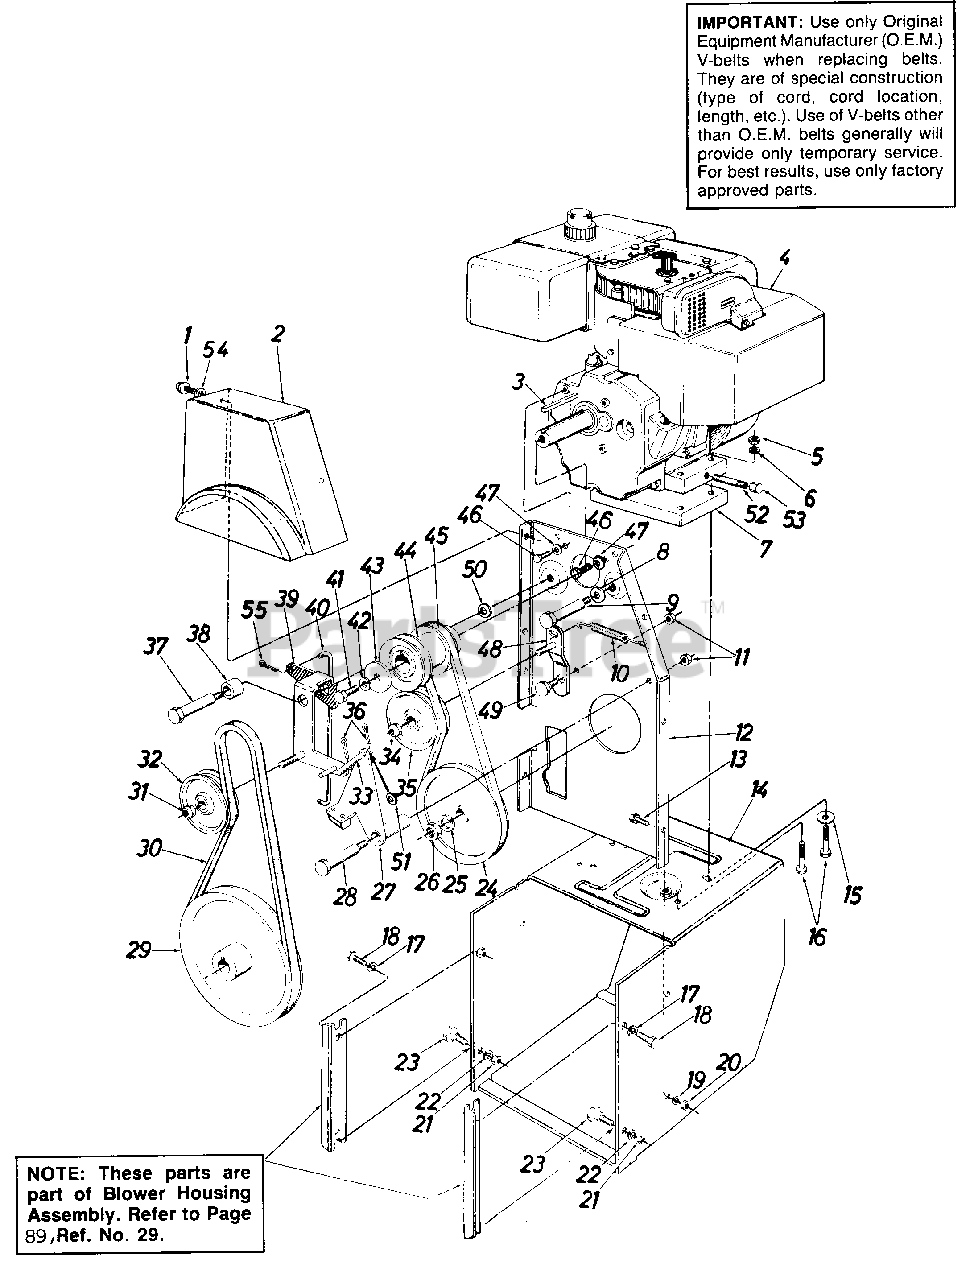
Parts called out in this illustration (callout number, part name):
1	Hex AB-Tap Scr. 5/16 x .75" Lg.
2	Belt Cover
3	Sq. Key 1/4" x 1.50" Lg.
4	Engine
5	Hex Nut 5/16-18 Thd.
6	L-Wash. 5/16" I.D.
7	Engine Spacer Ass'y.
8	Bell-Wash. .40 I.D. x .88 O.D.
9	Shld. Bolt .498" Dia. x 3.00" Lg.
10	Ext Spring .38 O.D. x 3.18" Lg.
11	Hex Cent. L-Nut 3/8-16 Thd.
12	Engine Brkt. Ass'y.
13	Hex Sems Scr. 5/16-18 x .75" Lg.
14	Frame Ass'y.
15	Fl-Wash. .345 I.D. x .75 O.D. x .060
16	Hex Bolt 5/16-18 x 2.50" Lg.
17	L-Wash. 3/8n I.D. H.D.
18	Pilot Scr. 3/8-16 x .88" Lg.
19	L-Wash. 5/16" I.D.
20	Hex Nut 5/16-18 Thd.
21	Hex Nut 3/8-16 Thd.
22	L-Wash. 3/8" I.D. H.D.
23	Shld. Bolt 498n Dia. x 840n Lg.
24	V-Pulley .628 I.D. x 7.50 O.D.
25	L-Wash. for 5/8n I.D.
26	Hex Ins. Jam L-Nut 5/8-18 Thd.
27	Brake Brkt. Ass'y.
28	Shld. Bolt 498n Dia. x 2.00" Lg.
29	V-Pulley .875 I.D. x 10.12 O.D.
30	"V"-Belt
31	Hex Ins. Jam L-Nut 3/8-24 Thd.
32	Fl-Idler w/Flanges 3.0 O.D.
33	Brake Linkage Ass'y.
34	Hex Ins. Jam L-Nut 3/8-24 Thd.
35	3.0" O.D. Fl-Idler w/Flanges
36	Int. Cot. Pin 8132n Dia.
37	Shld. Bolt .625" Dia. x 2.750" Lg.
38	Spacer .75 O.D. x 1.00" Lg.
41	Hex Bolt 3/8-24 x 1.25" Lg.
42	L-Wash. 3/8" I.D. H.D.
43	Fl-Wash.
44	Engine Pulley-Double Groove
45	"V"-Belt
46	Hex Bolt 5/16-24 x .62" Lg.
47	Bell-Wash. .345 I.D. x .88 O.D. x .060
48	Drive Idler Brkt. Ass'y.
49	Shld. Bolt-.625" Dia. x .170 Lg.
50	Bell-Wash. .40 I.D. x 1.12 O.D.
51	Fl-Wash. .385" I.D. x .620" O.D.
52	Pipe Nipple-1/4" Pipe Thd. x 3.5" Lg.
53	Hex Hd. Cap 1/4-18 Pipe Thd.
54	Fl-Wash. .340 I.D. x .62 O.D. x .62
55	Int. Cot. Pin 5/16" Dia.
